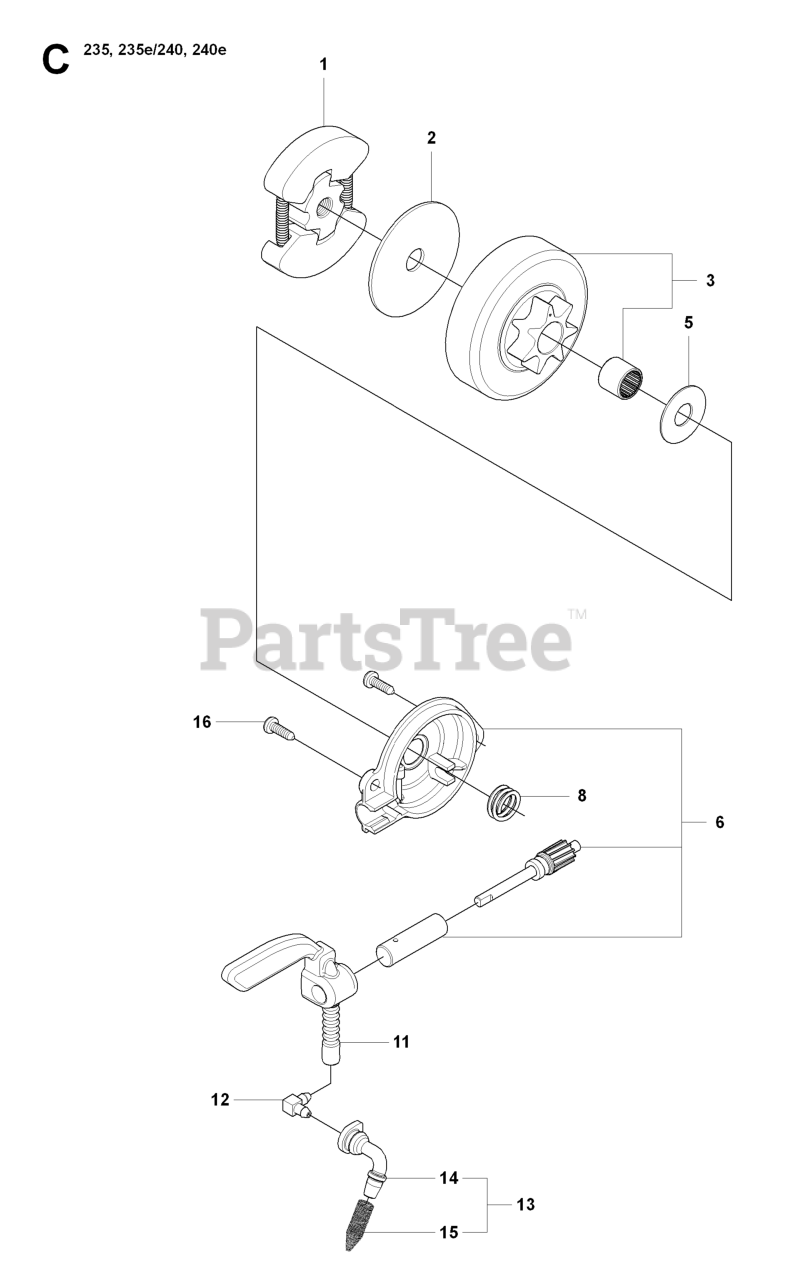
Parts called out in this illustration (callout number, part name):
1	CLUTCH ASSEMBLY
2	FRICTION DISC,CLUTCH 36/41
3	CLUTCH DRUM ASSY
3	ASSY CLUTCH DRUM .325"
5	THRUST WASHER
6	PUMP
11	OIL BLOCK
13	PICK UPS ASSY OIL TANK
14	SEAL PICKUP
15	SCREEN/FILTER
16	SCREW
